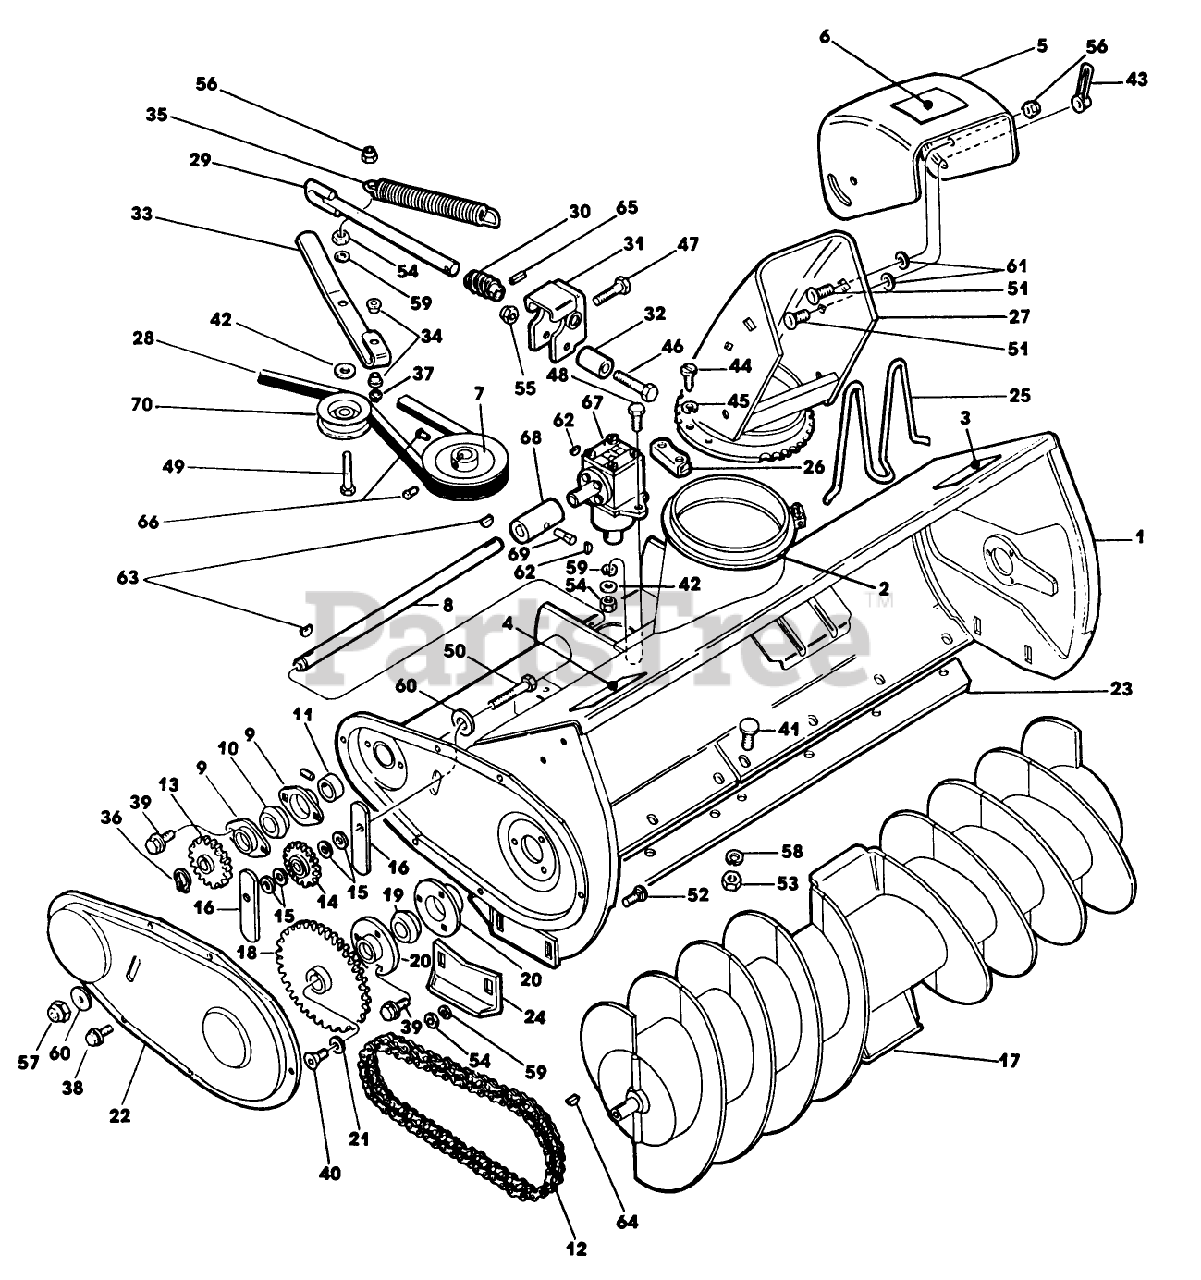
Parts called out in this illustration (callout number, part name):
7	PULLEY
9	FLANGETTE-BEARING
10	DISCONTINIUED
11	COLLAR-BEARING
13	SPROCKET ASSEMBLY
15	SPACER
24	SKID
26	RETAINER
28	V-BELT SECONDARY
34	BUSHING
36	RING-RETAINING
37	SNAP RING
42	WASHER
44	SCREW
53	NUT SS
54	NUT
55	NUT-LOCK, CONE
56	NUT-LOCKING
57	NUT-HEX CONE LOK
59	WASHER
70	PULLEY - IDLER
